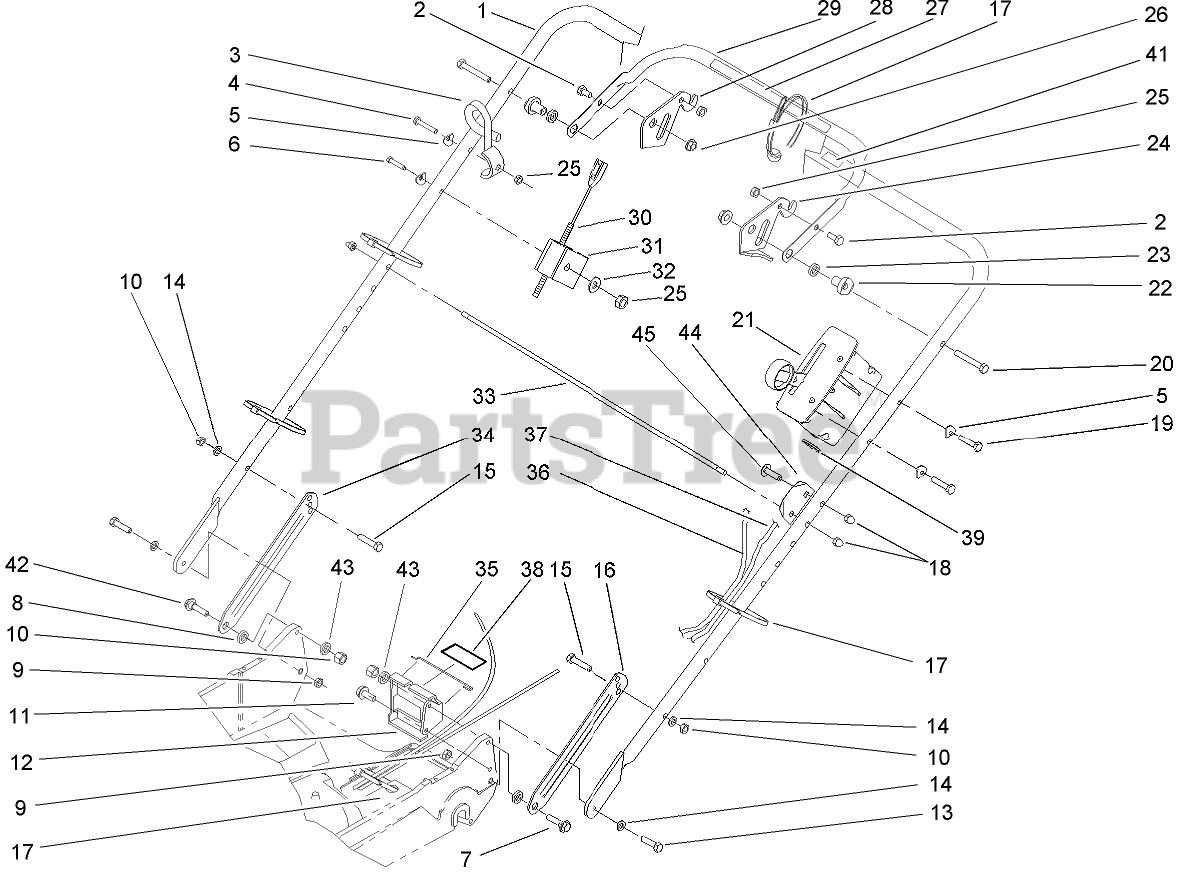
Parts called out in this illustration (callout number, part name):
2	SCREW-HH
3	GUIDE-ROPE
4	SCREW-HH
5	WASHER
6	SCREW-HH
7	SCREW-SHOULDER
8	SPACER
9	NUT-LOCK, NI
10	NUT-LOCK, NI
11	SCREW-HWHTF
12	BRACKET-ADJUSTMENT, TRACTION
13	SCREW-HH
14	WASHER-BELLEVILLE
15	SCREW-HH
16	LATCH-HANDLE, LH
17	TIE-CABLE
18	NUT-CAP
19	SCREW-HH
20	SCREW-HH
21	CONTROL-HEAD, THROTTLE
22	SPACER-SUPPORT
23	SPACER-NYLON
24	LEVER-CONTROL
25	NUT-LOCK, NI
26	NUT-LOCK, NI
27	Decal-Traction
28	LEVER-CONTROL
29	BAR-CONTROL
30	CABLE-BRAKE
31	SUPPORT-CABLE
32	WASHER-FLAT
33	ROD-SUPPORT, BAG
34	LATCH-HANDLE, RH
35	RETAINER-CABLE
36	CABLE-TRACTION
37	THROTTLE CABLE ASM
38	DECAL-POSITION, GEAR
39	E-RING
41	DECAL-PROTECTION, EAR
42	SCREW-SHOULDER
43	WASHER-PLAIN
44	PLATE-ALIGNING, BAG
45	SCREW-CARR
